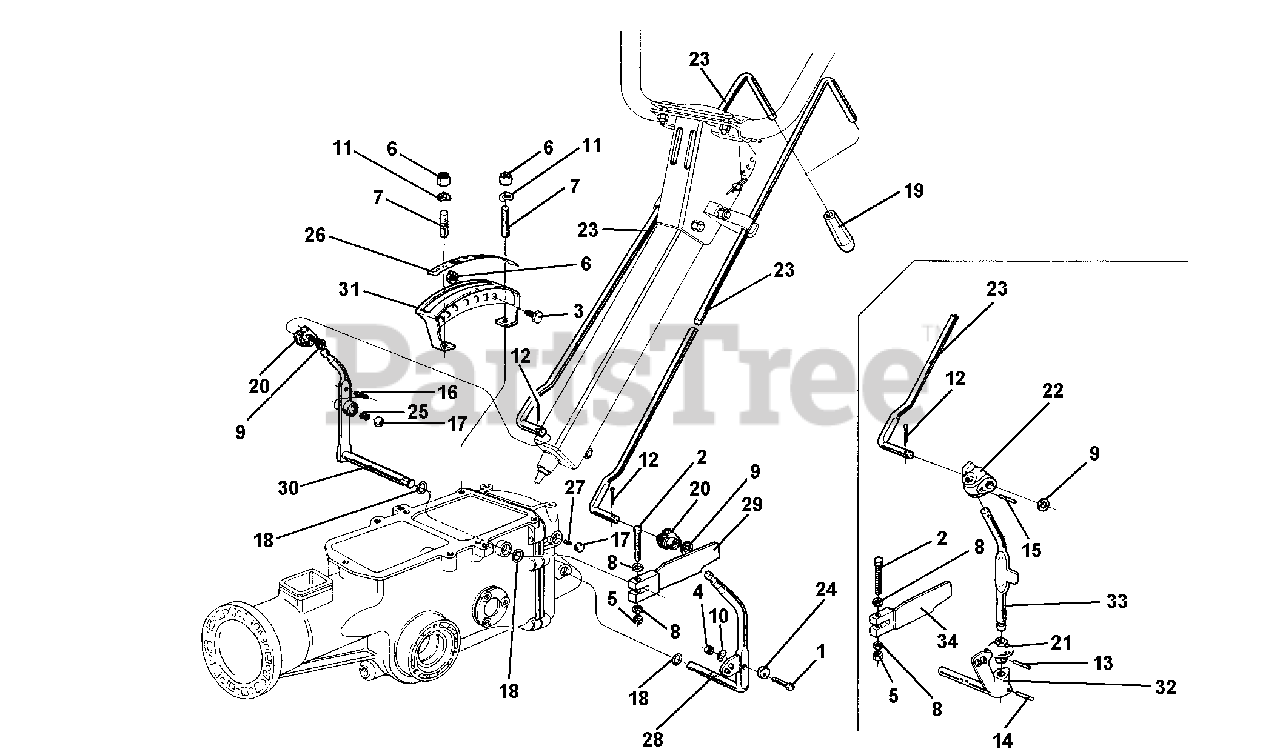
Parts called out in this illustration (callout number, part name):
1	SCREW M6 X 25
2	SCREW M6 X 40
3	SCREW M8 X 14
5	NUT, SELF LOCKING M6
6	NUT, SELF LOCKING M8
7	STUD M8 X 38 X 14 X 20
8	WASHER, FLAT 6.4
9	WASHER P10.5 X 18
10	WASHER, LOCK 6.4
11	WASHER, LOCK 8.4
13	LOCKING PIN 4 X 20 SPIRAL
15	LOCKING PIN 4 X 24 SPIRAL
16	LOCKING PIN SPIRAL
17	BALL 15/32 RIV RB-11.906
18	O-RING 115 11.91 X 2.62
20	JOINT, D 10
21	P.T.O. STOP RING
22	P.T.O. ARTICULATION
23	ROD, CONTROL, POWER TILLER
26	PLATE, SPEED, POWER TILLER
27	P.T.O. SPRING
28	P.T.O. LEVER
29	P.T.O. LOCKOUT
30	GEARBOX LEVER
32	P.T.O. CONTROL PIN
33	P.T.O. CONTROL LEVER
34	P.T.O. LOCKOUT
